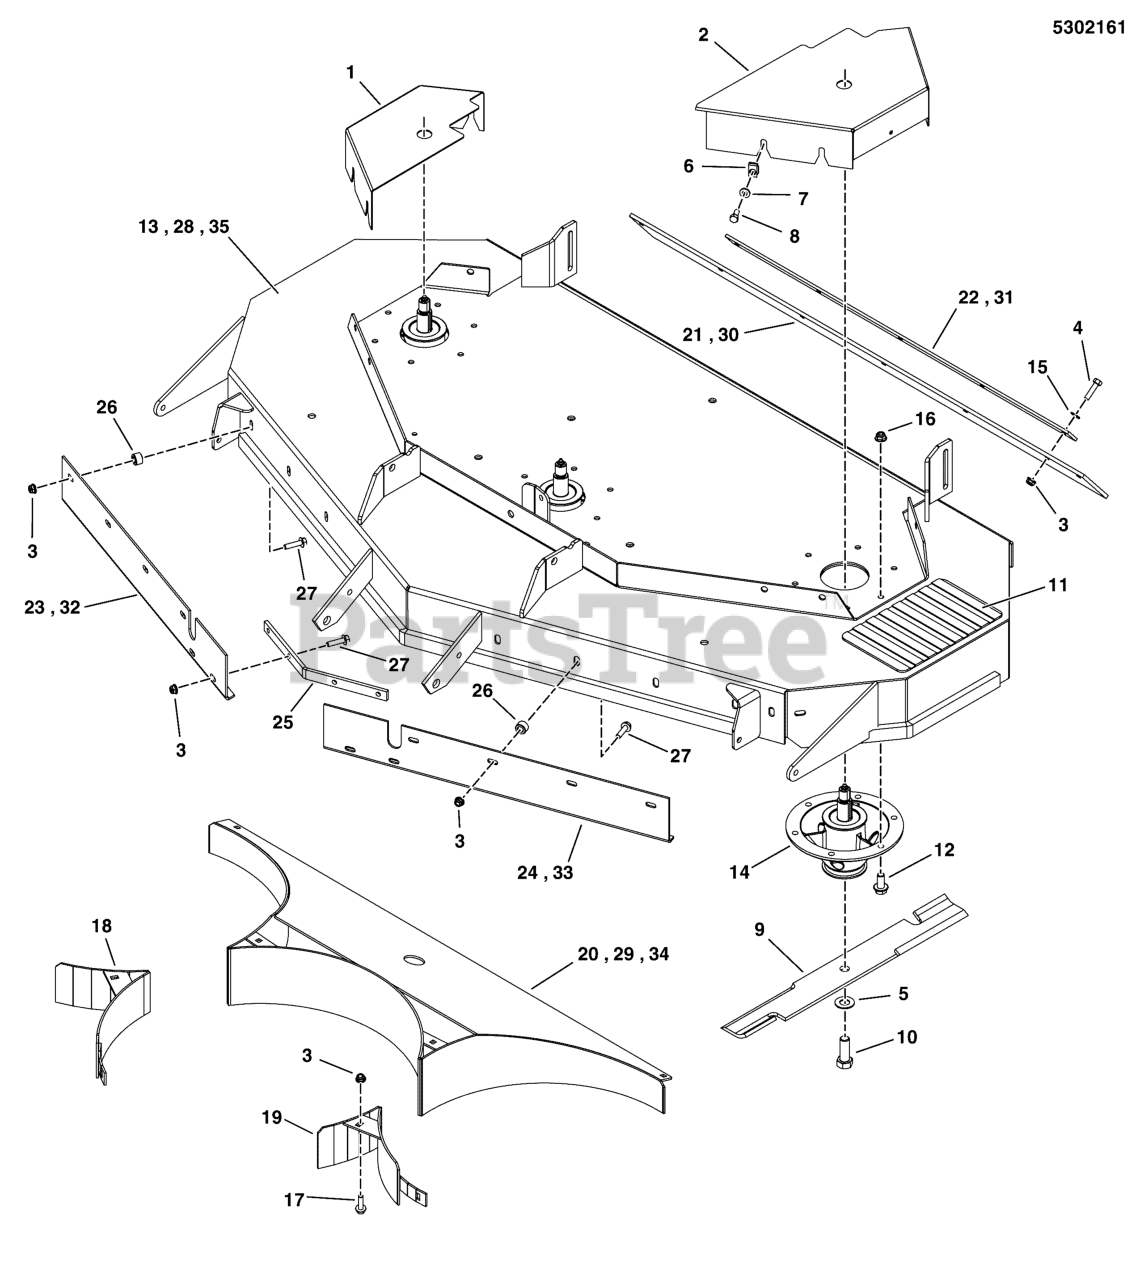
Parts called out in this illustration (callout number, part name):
1	GUARD, 61", RH - RED
2	GUARD, 61 - LH - RED
3	NUT, 5/16-18 HEX NYLOCK FLANGE
4	BOLT, 5/16-18 X 1-1/4 GD5 YZ
5	WASHER, 5/8 GRADE 8, YZ
6	BODY CLIP, 5/16-18-7GA MATERIAL
7	WASHER, 5/16" SAE
8	BOLT, 5/16-18 X 3/4 GD5
9	BLADE, 21
10	BOLT, 5/8-11 X 1-3/4 GD8
11	SAFETY WALK, 9.75 X 6.00
12	BOLT, 3/8-16 X 1, FLANGE, GD 5, CZ
13	DECK SHELL W/DECALS, 2500-61RDCE (5413219B)
14	SPINDLE ASSM, CAST IRON 8.0-6 BOLT
15	WASHER, 5/16" SAE
16	NUT, 3/8-16 HEX NYLOCK FLANGE
17	BOLT, 5/16-18 X 1, CARRIAGE
18	WELD, FRONT BAFFLE, 61 RD, RH - BLK
19	WELD, FRONT BAFFLE, 61 RD, LH - BLK
20	WELD, REAR BAFFLE, 61 RD - BLK
21	FLAP, STRIPER, RD
22	PLATE, SUPPORT - BLK
23	BAFFLE, BLOWOUT, RH
24	BAFFLE, BLOWOUT, LH
25	BAFFLE, REINFORCEMENT - BLK
26	SPACER, .39 X .75 X .50, CZ
27	BOLT, 5/16-18 X 1 1/4 FLANGE
28	DECK SHELL W/ DECALS, IS2500 61RD CE (5407877B)
29	WELD, REAR BAFFLE, 61 RD - BLK
30	FLAP, STRIPER, 61, RD
31	PLATE, SUPPORT, 61 - RED
32	BAFFLE, BLOWOUT, RH
33	BAFFLE, BLOWOUT, LH
34	WELD, REAR BAFFLE, 61RD - RED
35	DECK SHELL W/ DECALS, IS2500 61RD CE (5406725B)
